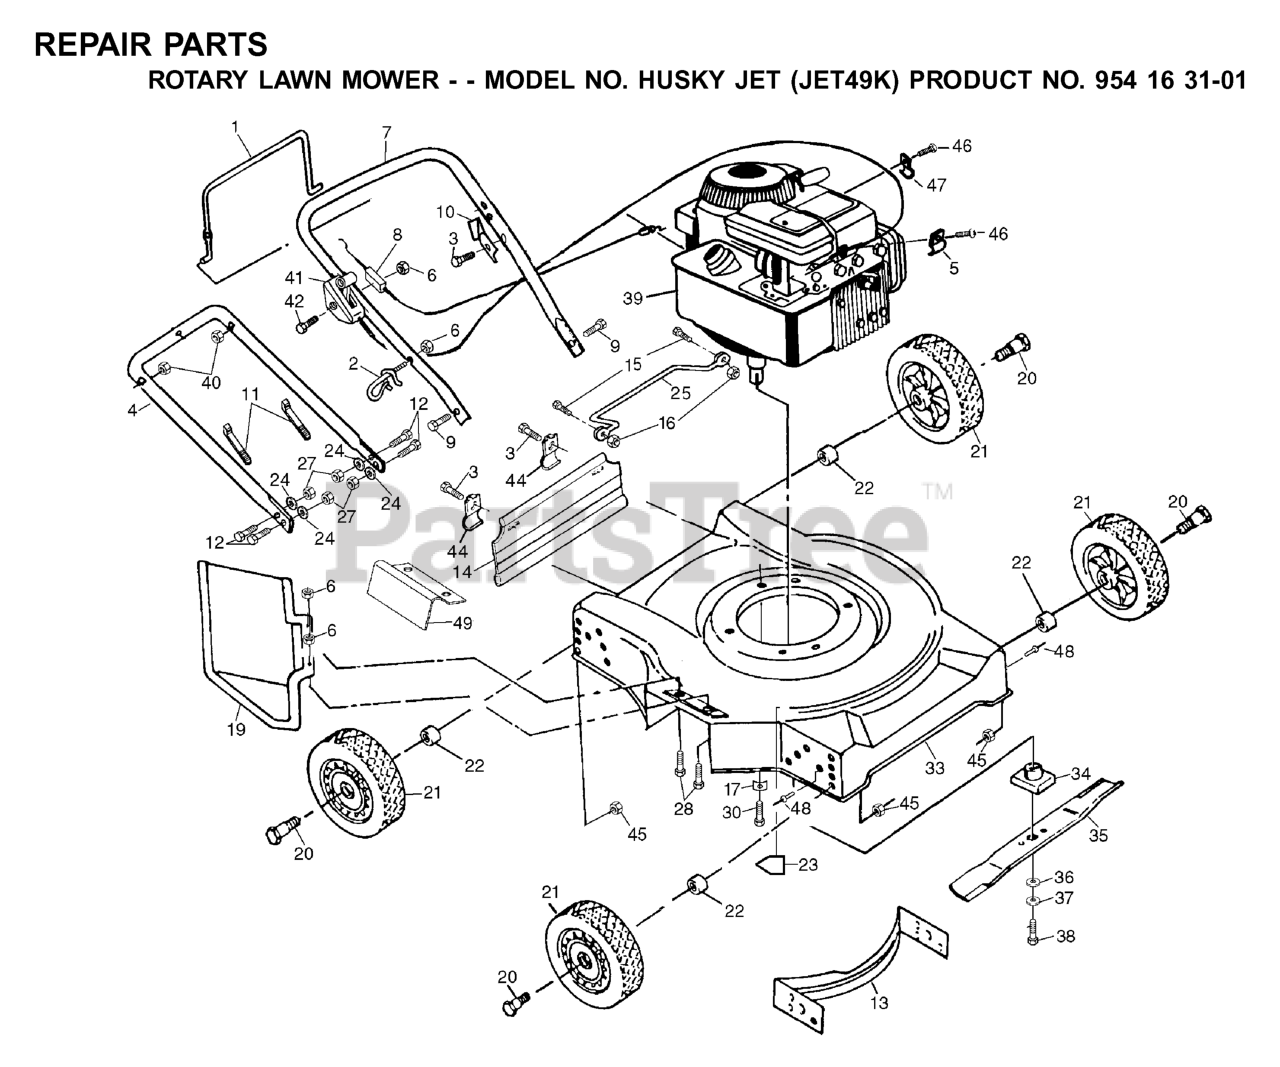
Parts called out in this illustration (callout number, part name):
1	CONTROL BAR
2	ROPE GUIDE
3	TAPPING SCREW
5	WASHER
6	NUT
8	CABLE.CONTROL.MZR.RH.SP/PUSH
9	BOLT
10	BRACKET UPSTOP
11	TIE GUIDE
13	FRONT BAFFLE
14	REAR SKIRT
15	REPL BY 817 02 10-08
17	WASHER.ENGINE.BZP
21	WHEEL
22	SPACER.WHEEL.390.X1.0X.380.RTA
23	DECAL MOWER CUT/FINGER
27	FLANGED LOCKNUT 3/8-16 ZINC
28	BOLT.HEX.1/4.X.3/4.DICHROMATE
30	BOLT 3/8-16X1-1/8
34	BLADE ADAPTOR
35	20" Blade
36	WASHER,HARDEN
37	LOCKWASHER
38	SCREW, HEX HD 3/8-24 X 1-3/8
40	NUT
41	THROTTLE CONTROL
42	SCREW.PAN.HEAD
44	BRACKET DEFL PM
45	LOCKNUT PM
46	SCREW.HEX.HEAD.WASHER.10-16
47	GUIDE CLIP PM
48	RIVET BLIND
